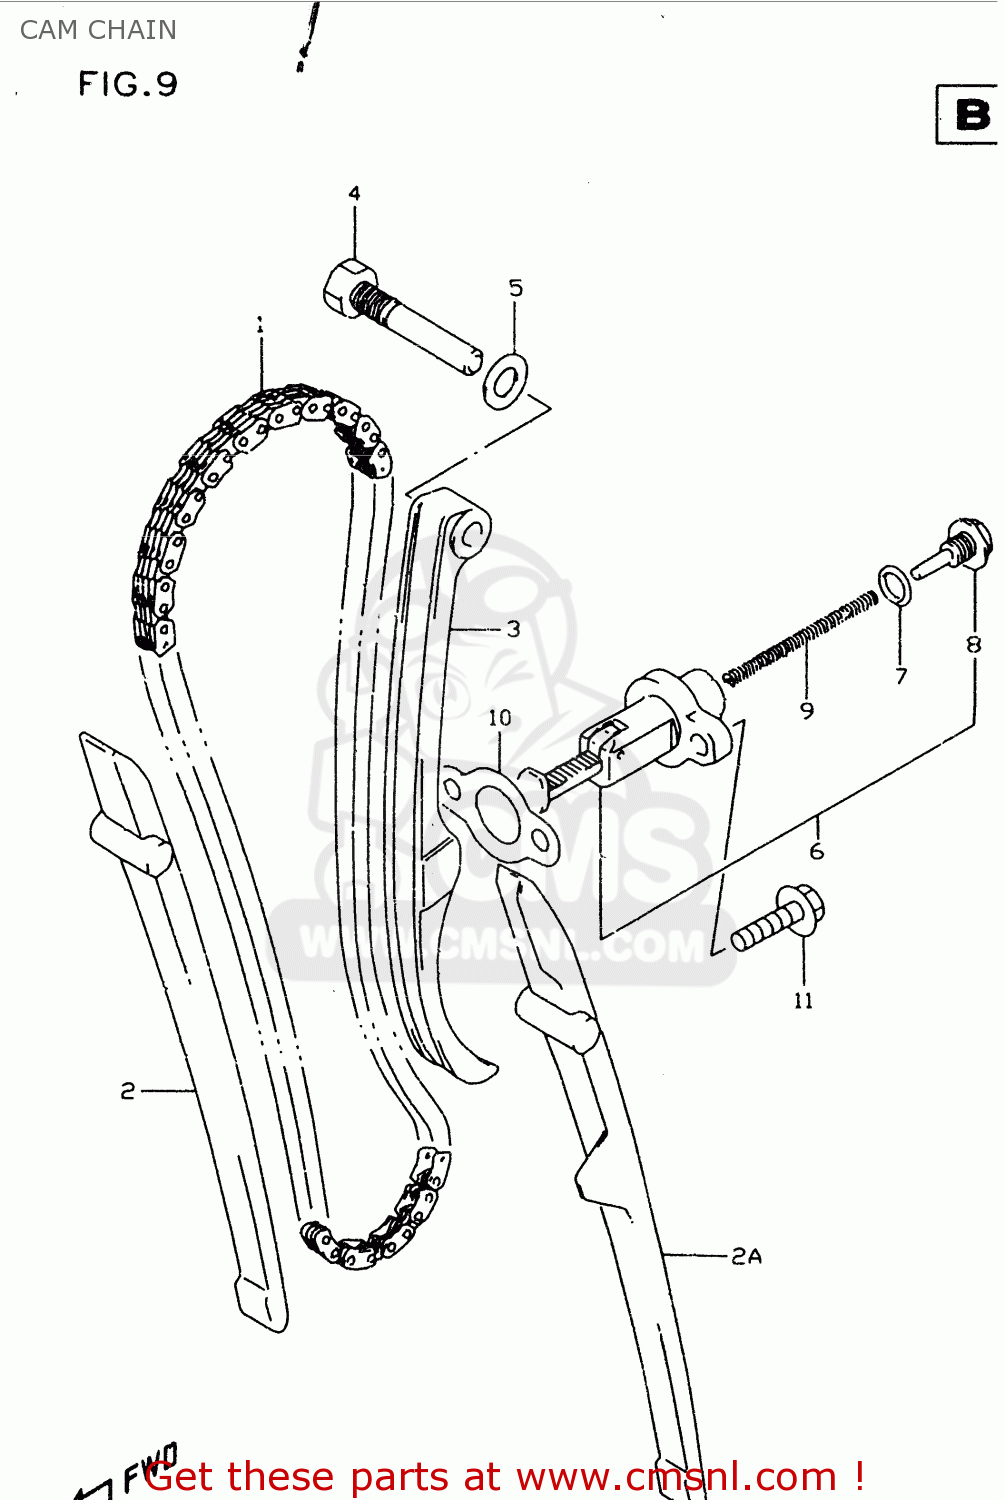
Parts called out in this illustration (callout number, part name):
1	CHAIN,CAMSHAFT DRIVE
2	GUIDE,CAM CHAIN
2A	GUIDE,CAM CHAIN
3	TENSIONER,CAM CHAIN
4	BOLT,CAM CHAIN TENSIONER
5	GASKET 8.2X14X1 (NAS)
6	ADJUSTER ASSY,TENSIONER
7	O RING
8	PLUG,ADJUSTER
9	SPRING
10	GASKET,TENSIONER ADJUSTER (NAS)
11	BOLT
